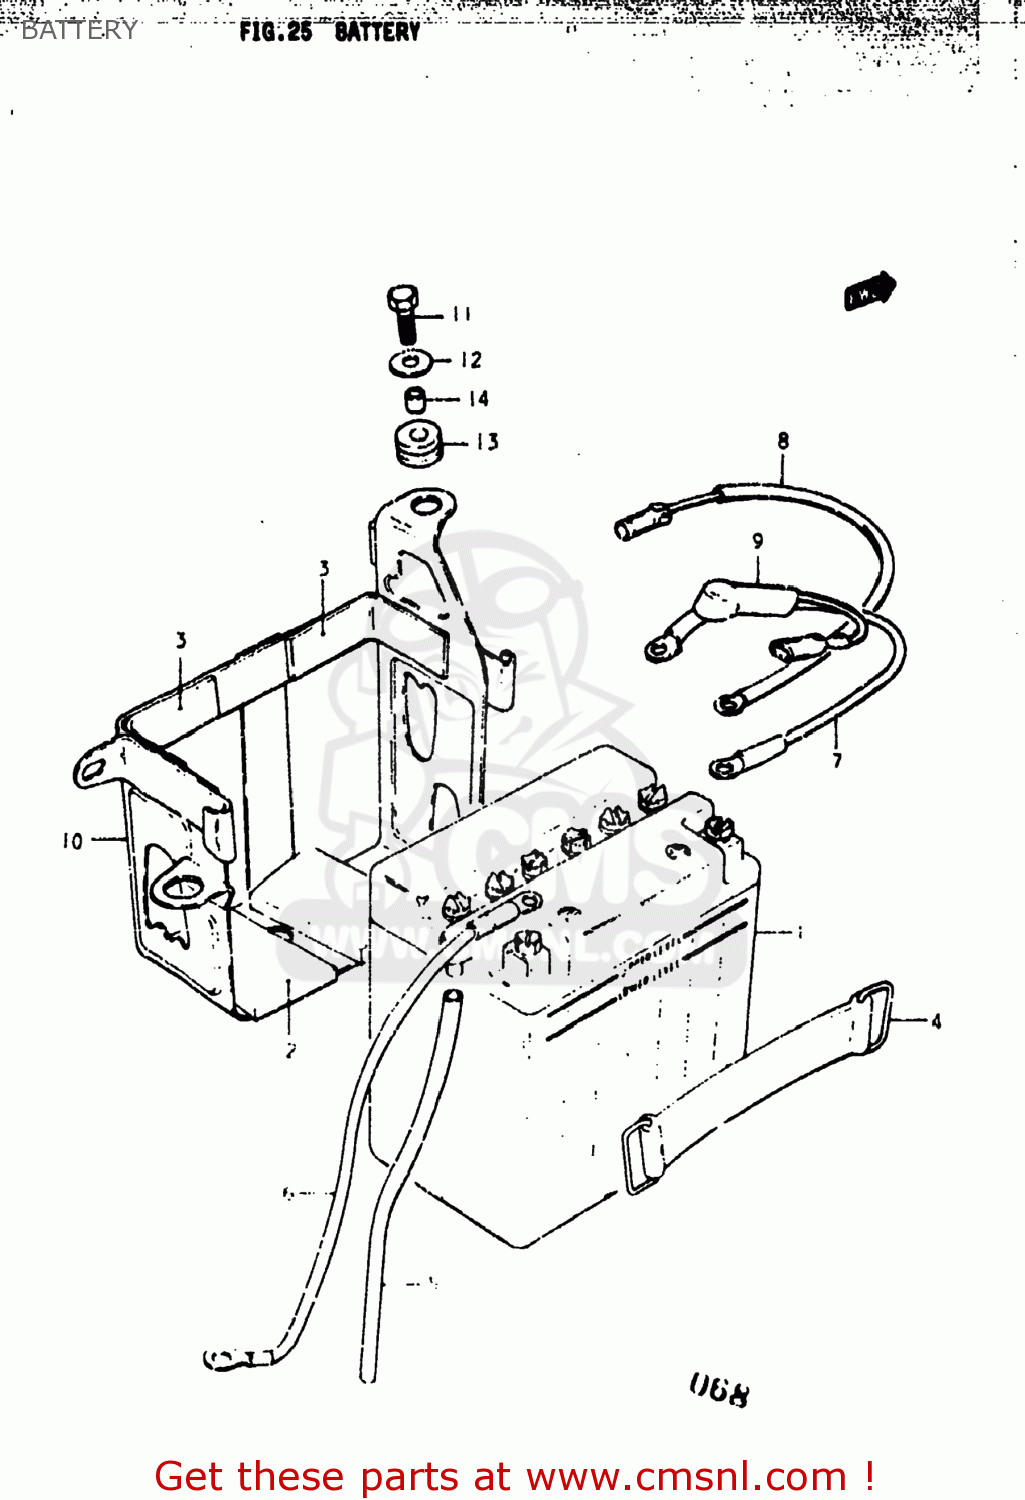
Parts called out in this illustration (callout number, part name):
1	BATTERY ASSEMBLY
2	CUSHION,BATTERY
3	PROTECTOR,20X9
4	BAND
5	HOSE,BATTERY EXHAUST
6	CORD,BATTERY MINUS
7	WARE,BATTERY PLUS
8	WIRE
9	CAP,STARTER RELAY
10	HOLDER,BATTERY
11	BOLT
12	WASHER
13	CUSHION
14	SPACER (6.1X9X9)
